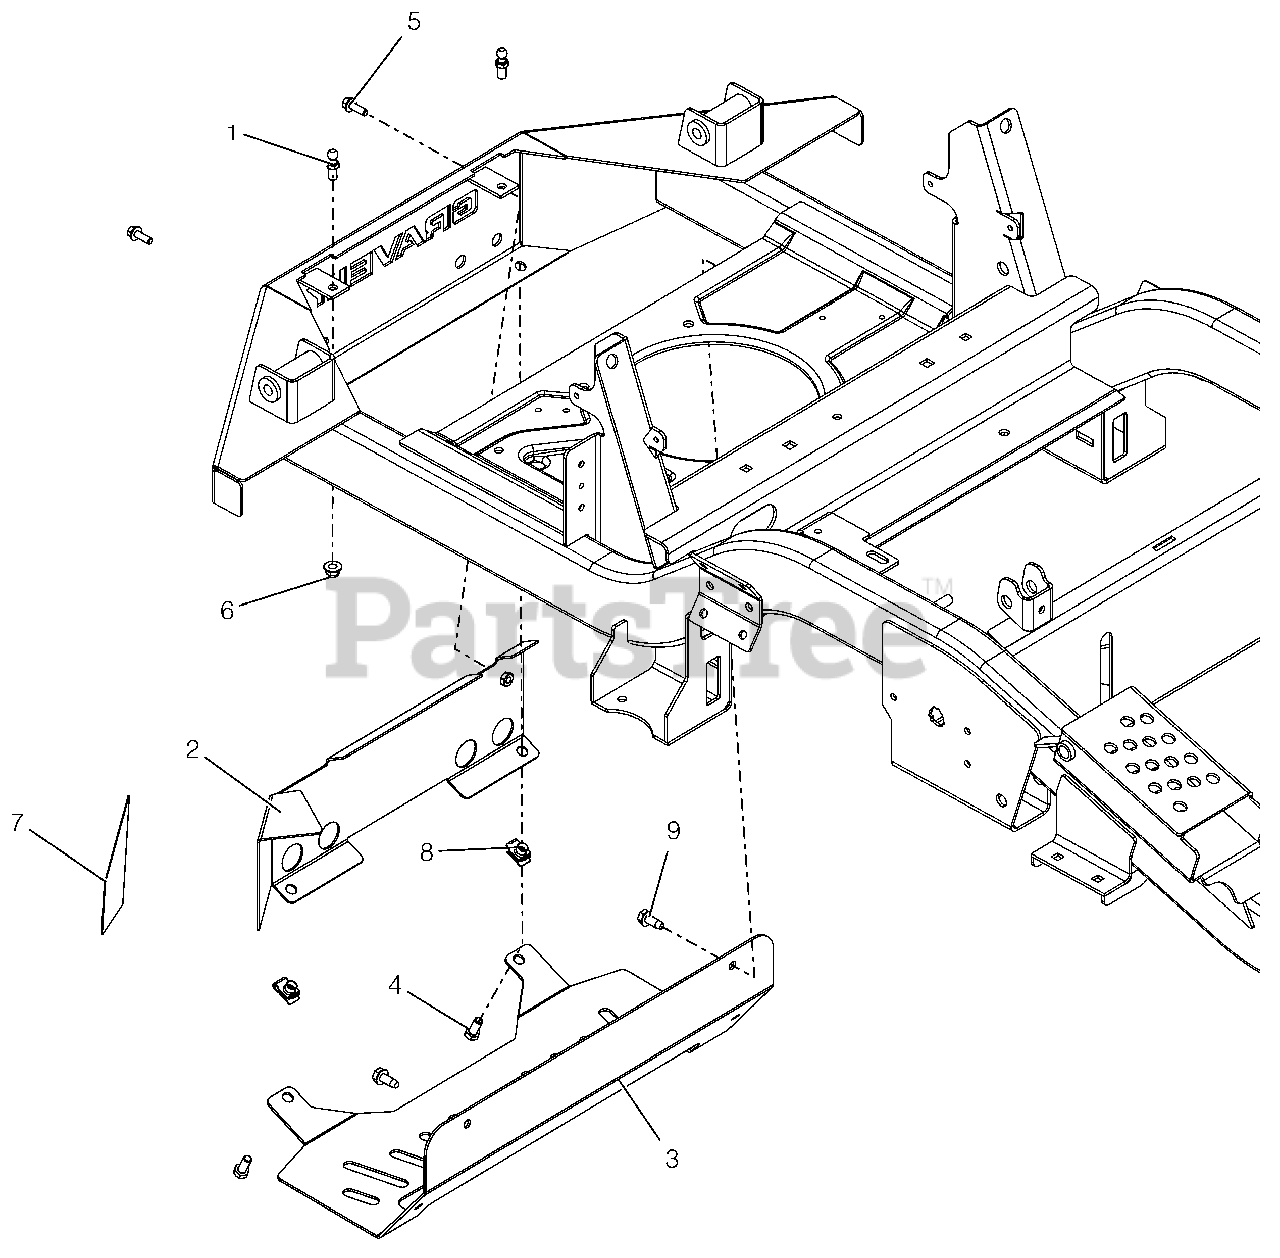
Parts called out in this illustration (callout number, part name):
1	STUD- BALL
2	WMT, HEAT BAFFLE
3	SHIELD, HEAT (HD)
4	@BLT-HEX .31-18X.75 GR5 YWZC
5	BLT,HEX-FLG .25-20X.75 G5 BFP
6	NUT,NYL-FLG .31-18 GF ZCC
7	TAPE, HEAT DEFLECTOR
8	NUT-CLIP RETAINER 5/16-18X.56
9	@SCR-TAP .31-18X.75 HWH TR YWZ
